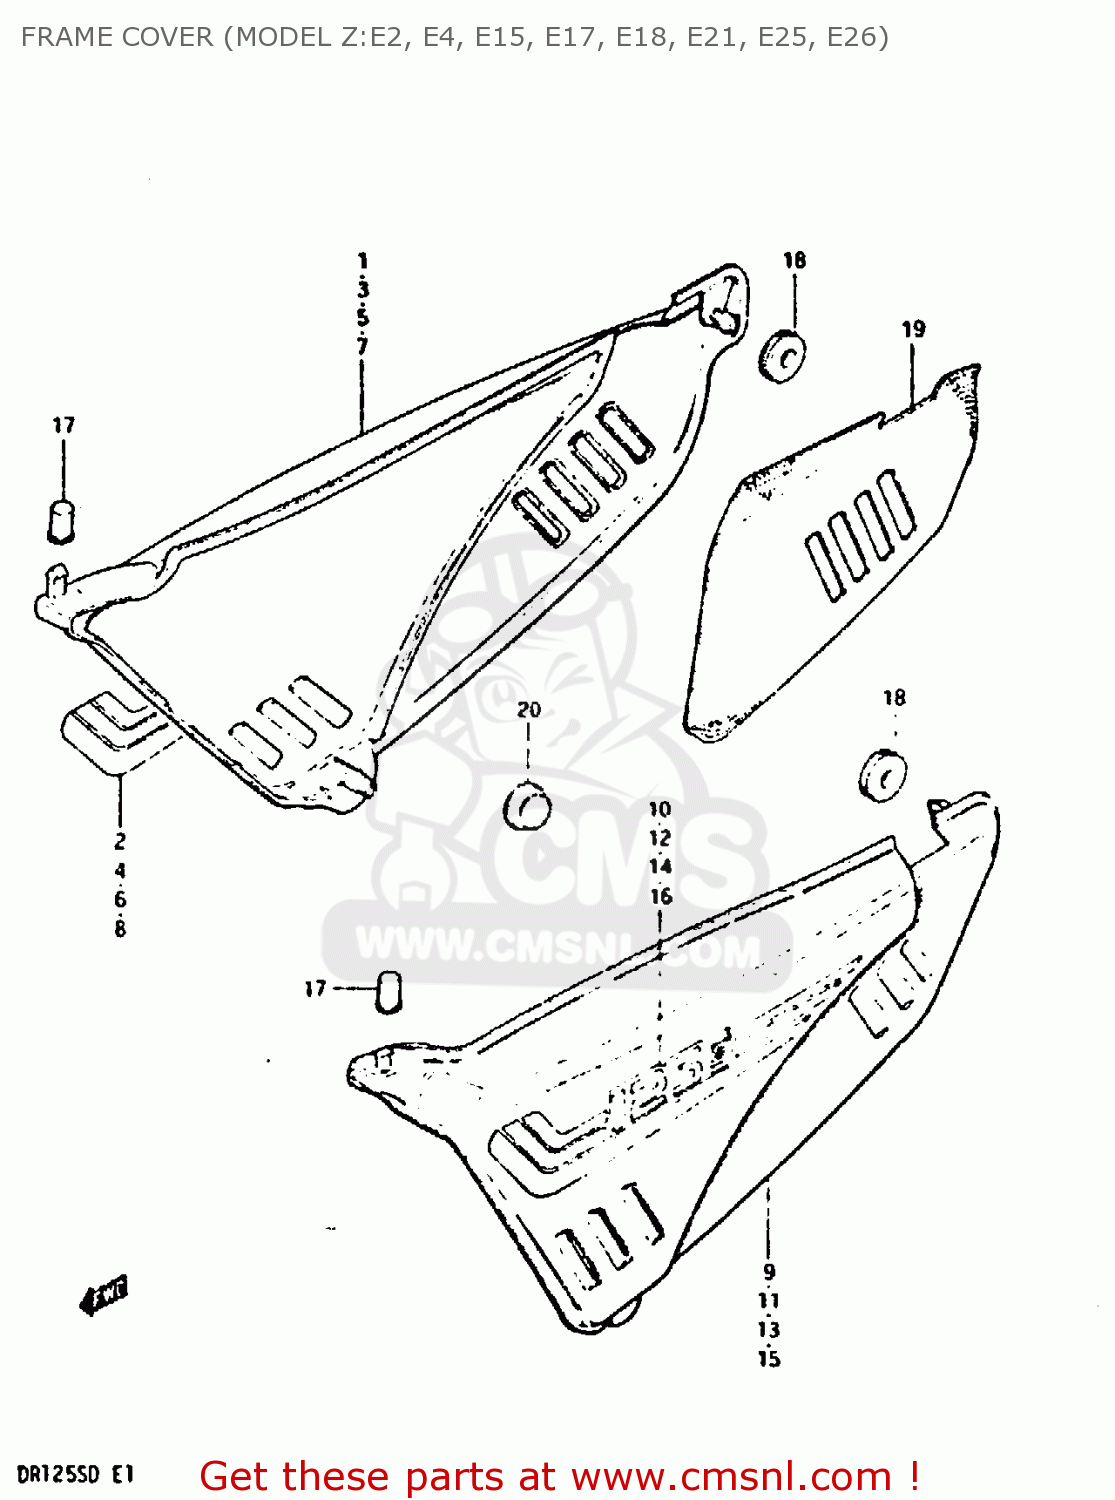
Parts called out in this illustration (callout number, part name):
1	COVER, FRAME RH (BLACK)
2	TAPE, RH
3	COVER, FRAME RH (BLUE)
4	TAPE, RH
5	COVER, FRAME RH (YELLOW)
6	TAPE, RH
7	COVER,FRAME,RIGHT
8	TAPE RH
9	COVER, FRAME LH (BLACK)
10	TRAPOE, LH
11	COVER, FRAME LH (BLUE)
12	TAPE, LH
13	COVER, FRAME LH (YELLOW)
14	TAPE, LH
15	COVER, FRAME LH (RED)
16	TAPE, LH
17	CUSHION
18	CUSHION
19	HEAT SHIELD,FRAME COVER
20	CUSHION
